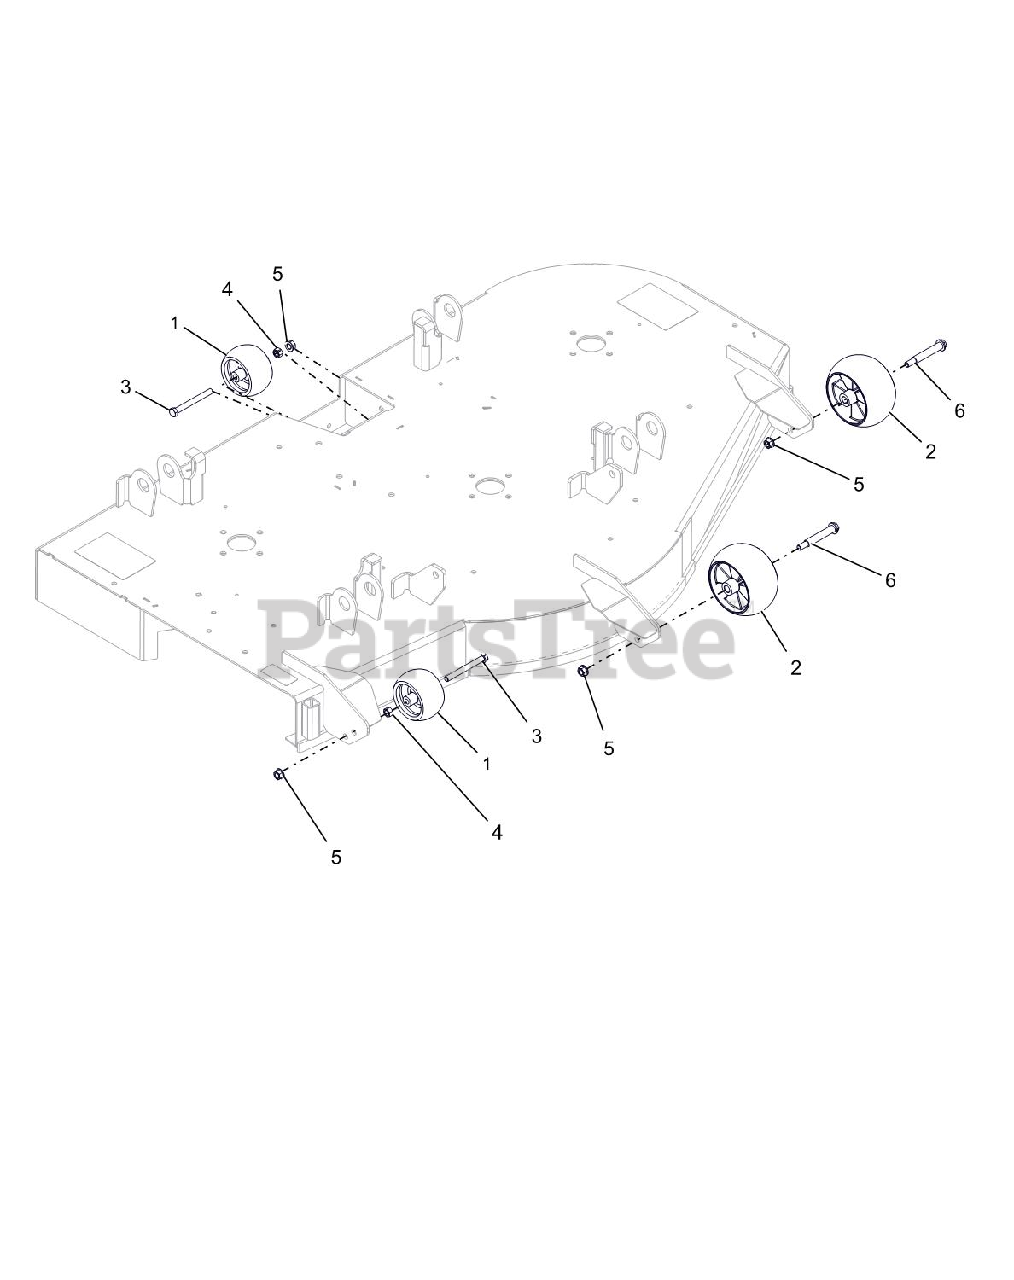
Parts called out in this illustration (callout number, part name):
2	ANTI-SCALP WHEEL - 5X OS
3	@BLT-HEX .38-16X3.50 GR5 YWZC
4	@NUT-HEX .38-16 YWZC
5	@NUT-LK-TOP-FLG .38-16 YWZC
6	BLT-SHLDR .38-16X2.50 HWH G5
